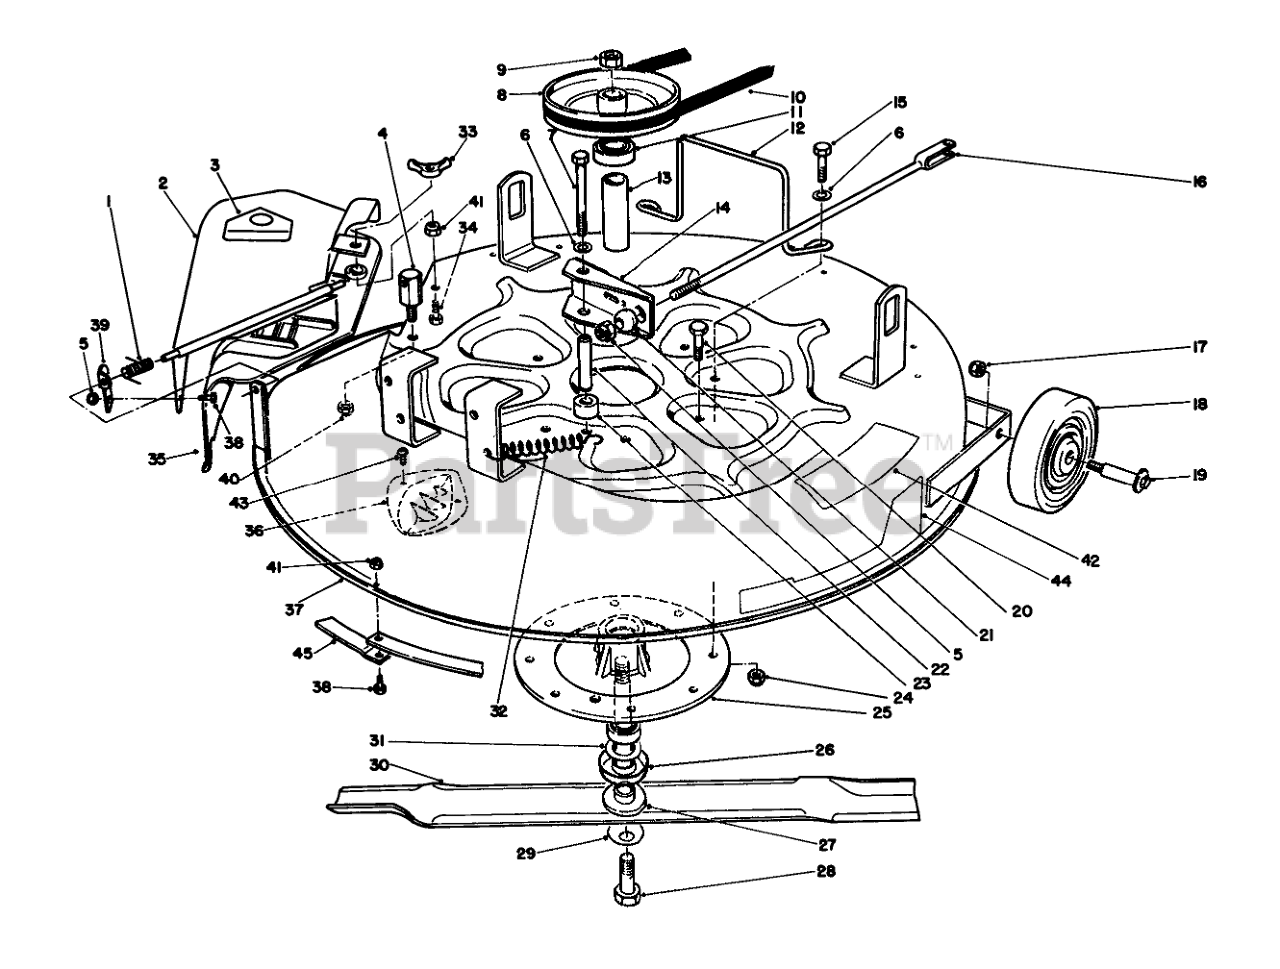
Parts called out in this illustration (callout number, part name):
1	SPRING
2	Deflector (Incl. Ref. #3)
3	DECAL-DANGER
4	POST-PIVOT
5	NUT-HEX
6	WASHER-PLAIN
7	SCREW-HH
8	PULLEY-DECK
9	NUT-HEX
10	V-Belt
11	BEARING-BALL
12	GUIDE-DECK BELT
13	SPACER-BEARING
14	DECK BRAKE ASSEMBLY
15	SCREW-HH
16	DECK BRAKE ROD WA
17	NUT-LOCK, NI
18	WHEEL-DECK
19	BOLT-WHEEL
20	SCREW-HH
21	BALL-SWIVEL, STOP
22	POST-BRAKE MTG
23	SPACER-DECK BRAKE
24	NUT-LOCK, NI
25	CASTING-SPINDLE
26	SHIELD-BEARING
27	SHAFT-SPINDLE
28	SCREW-HH
29	WASHER-BELLEVILLE
30	Blade
31	SPACER
32	SPRING-EXTENSION
33	Nut-Wing
34	SCREW-HHF
35	COVER- 25" (W/KICKER)
36	KICKER
37	Deck
38	SCREW-HH
39	Bracket-Detector
40	NUT-LOCK, NI
41	NUT-LOCK, NI
42	DECAL - DANGER
43	#8 X .625" PHILPS PAN H
44	DECAL - RECYCLER
45	Ring-Deck
